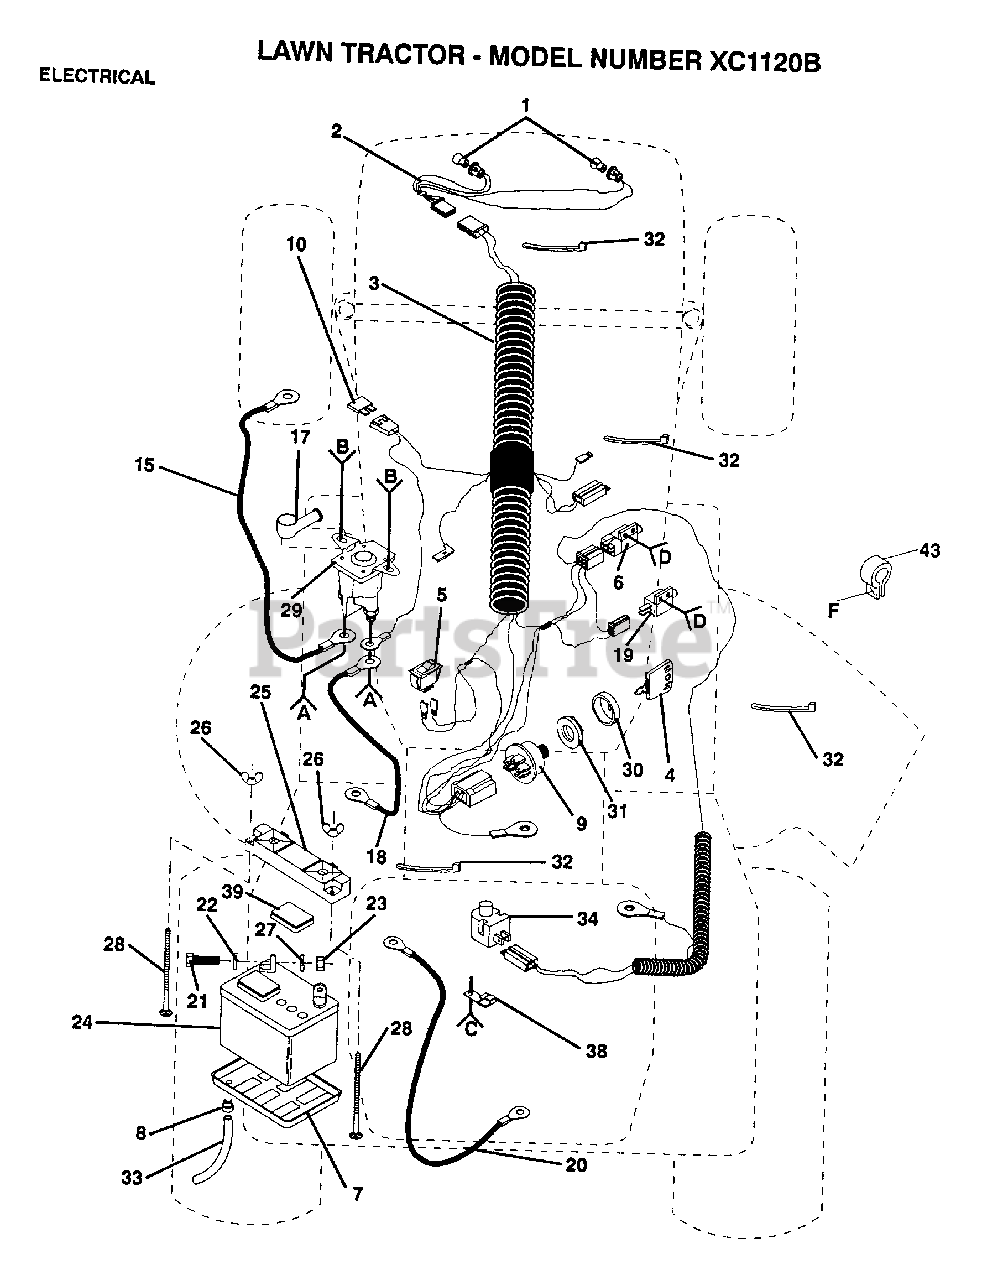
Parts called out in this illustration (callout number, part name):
3	"HARNESS,WIRING"
4	KEY
5	SWITCH LT
6	SWITCH-INTER. GT
7	"TRAY T, BATTERY"
8	HOSE CLAMP T
10	FUSE HYT
18	STARTER CABLE GT
19	SWITCH INTERLOCKT
21	BOLT LT
22	WASHER
27	LOCKWASHER
28	BOLT
32	WIRE TIE
34	SWITCH SEAT
39	"CAP,BATTERY "
43	INSUL CLIP T
